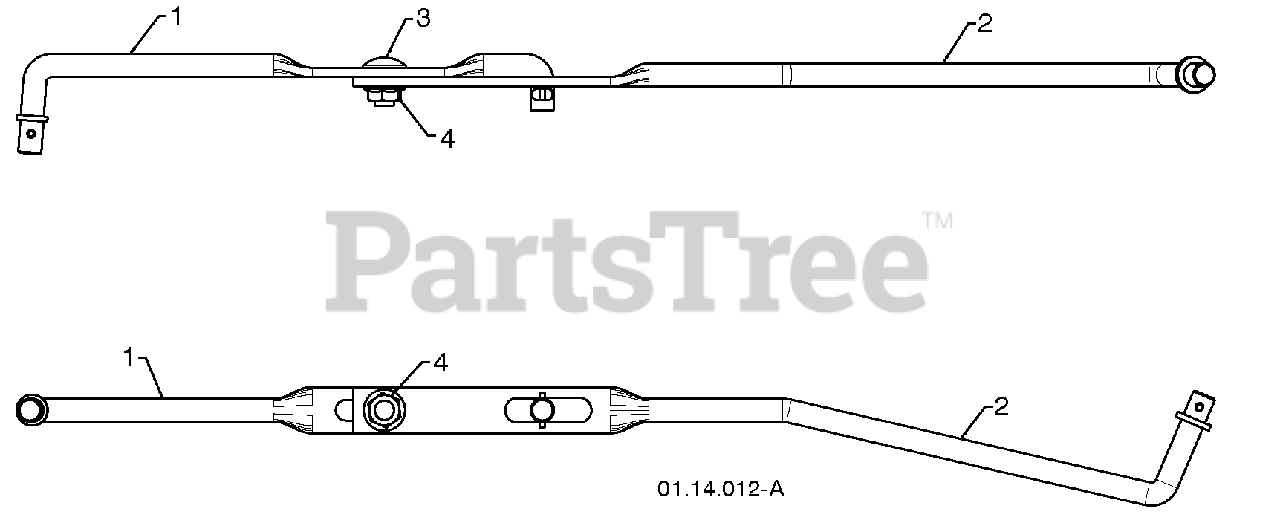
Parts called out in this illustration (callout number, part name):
1	SHIFTER ROD TOP
2	SHIFTER ROD BOTTOM
3	CARRIAGE BOLT 5/16-18 X .75
4	NUT 5/16-18
